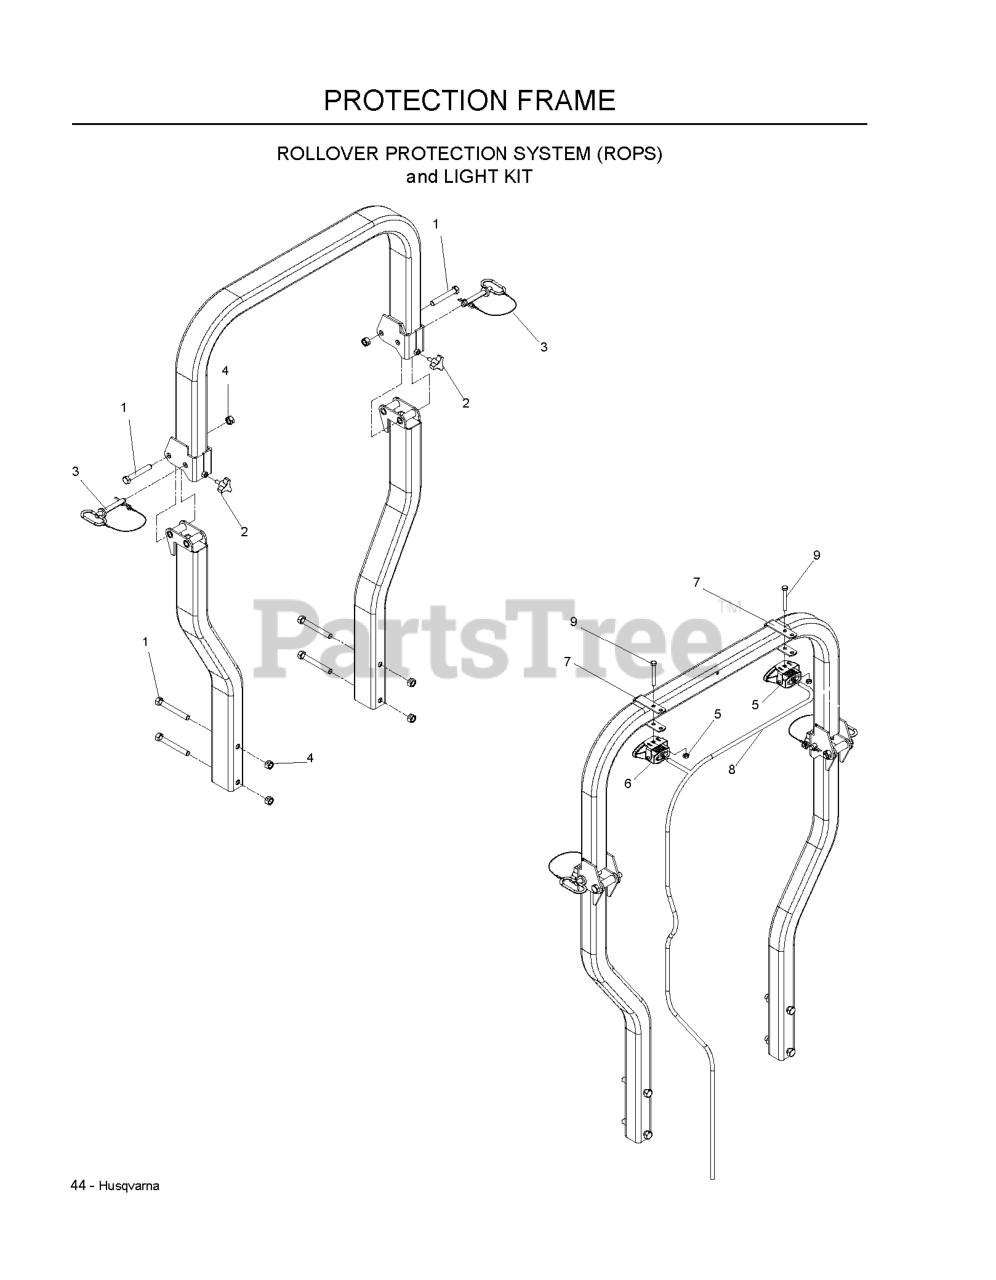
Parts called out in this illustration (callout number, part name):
1	HCS 1/2C X 3 1/4
2	KNOB W/STUD
3	PIN, 1/2" W/LANYARD
4	NUT 1/2-13 HEX CNTRLK GR 5 ZD
5	NUT 5/16-18 HEX JAM ZD
6	LIGHT 35W W/BRKT
7	LIGHT MOUNTING BRACKET
8	LIGHT HARNESS
9	BOLT 5/16C X 2 1/2
